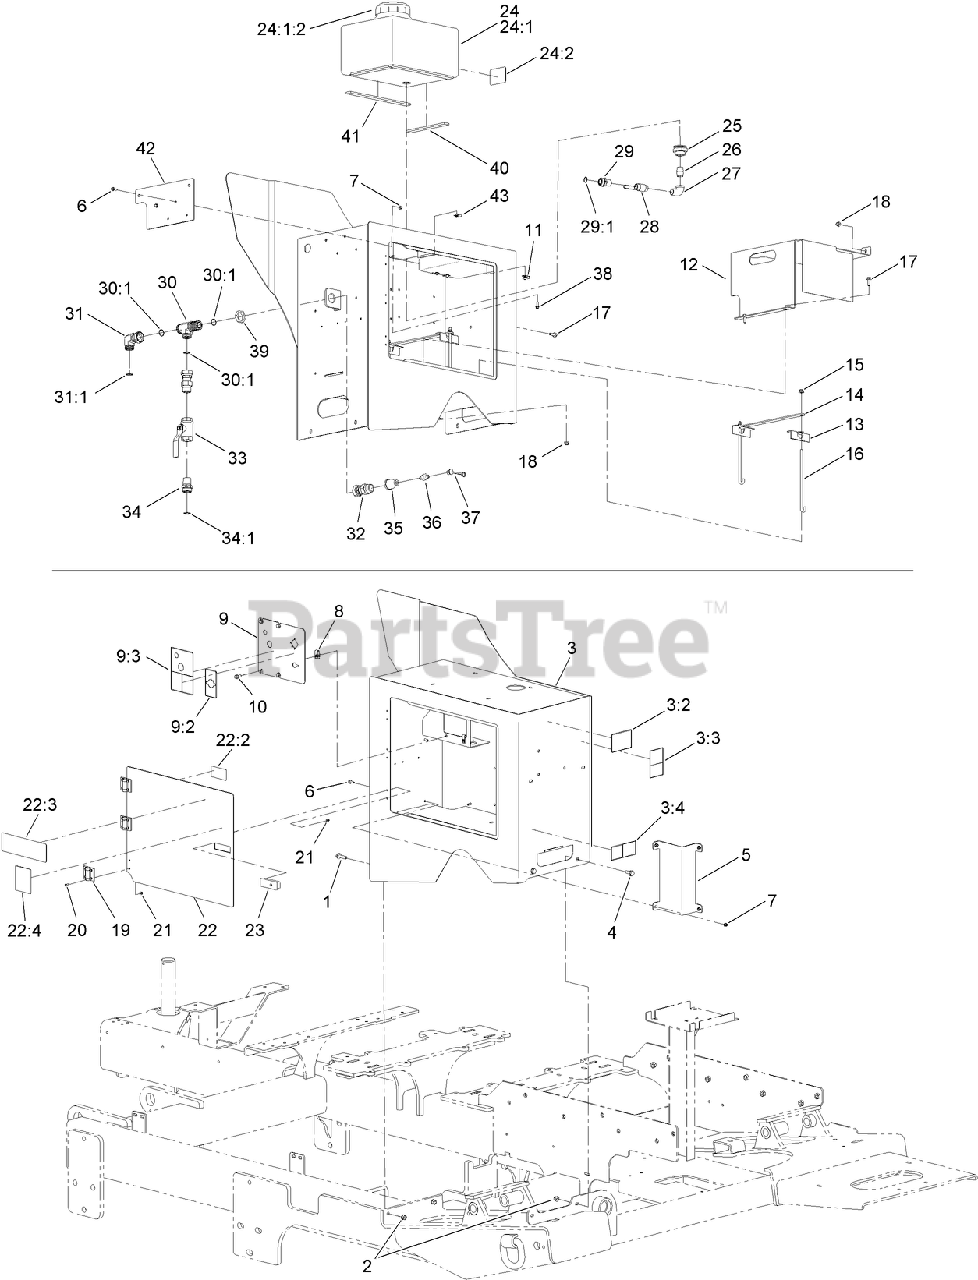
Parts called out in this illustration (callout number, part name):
1	SCREW-HHF
2	NUT-LOCK, NI
3	CONTROL BOX ASM
3:2	DECAL-RAISE AND LOWER
3:3	DECAL-DANGER, BACK UP
3:4	DECAL-WARNING, HYDRAULIC PRESSURE
4	SCREW-HHF
5	PLATE-CORNER, CONSOLE
6	SCREW-HHF
7	NUT-FLANGE, NI
9	CONTROL PLATE ASM
9:2	DECAL-DISCONNECT, BATTERY
9:3	DECAL-REAR CONTROLS OVERLAY
10	SCREW-HHF
12	PLATE-COVER
13	ANGLE-HOLDDOWN, BATTERY
14	PLATE-Battery Hold Down
15	NUT-HF, NI
16	BOLT-HOLDDOWN, BATTERY
17	SCREW-HHF
18	NUT-LOCK, HHF
21	NUT-HF
22	DOOR ASM
22:2	DECAL-WARNING, BATTERY
22:3	DECAL-SAFETY
22:4	DECAL-DANGER, NO RIDERS (REAR)
23	LATCH-TRIGGER, RAISED (W/LOCK)
24	ANTIFREEZE TANK ASM
24:1	TANK
24:1:2	LID-TANK
24:2	DECAL-ANTIFREEZE
25	FITTING-TANK, BULKHEAD (PLASTIC)
26	NIPPLE-STRAIGHT
27	ELBOW-STREET, 90 DEG
28	VALVE-BALL
29	FITTING-STRAIGHT
29:1	O-RING
30	FITTING-TEE, BULKHEAD
30:1	O-RING
31	FITTING-SWIVEL, 90 DEG
31:1	O-RING
32	FITTING-STRAIGHT
33	VALVE-BALL
34	FITTING-STRAIGHT
34:1	O-RING
35	FITTING-REDUCER
36	NIPPLE-CONNECT, QUICK
37	CAP-DUST, PLASTIC
38	SCREW-HHF
39	NUT-BULKHEAD
40	STRIP-SEAL
41	STRIP-SEAL
42	PLATE-LOCKOUT, CYLINDER
